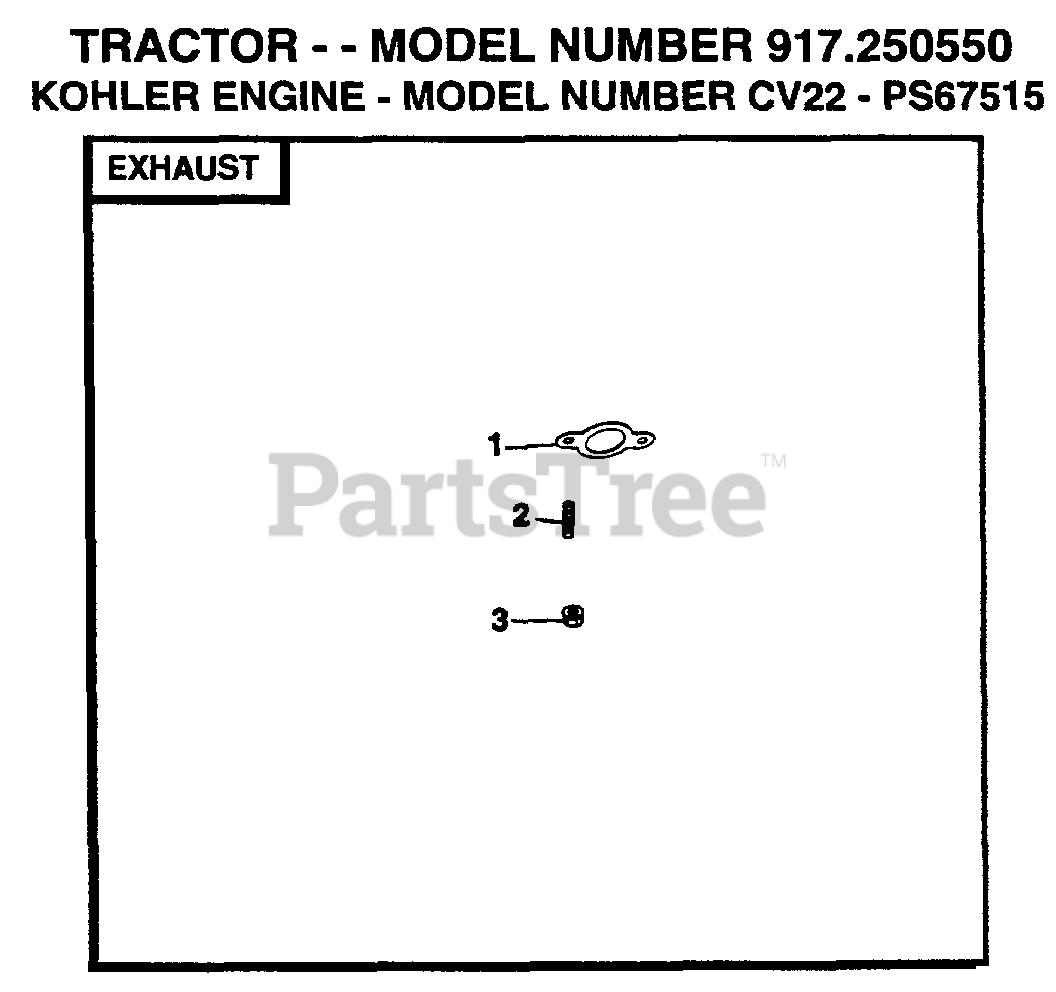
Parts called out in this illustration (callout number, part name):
1	GASKET
2	STUD. EXHAUST MANIFOLD
3	NUT
